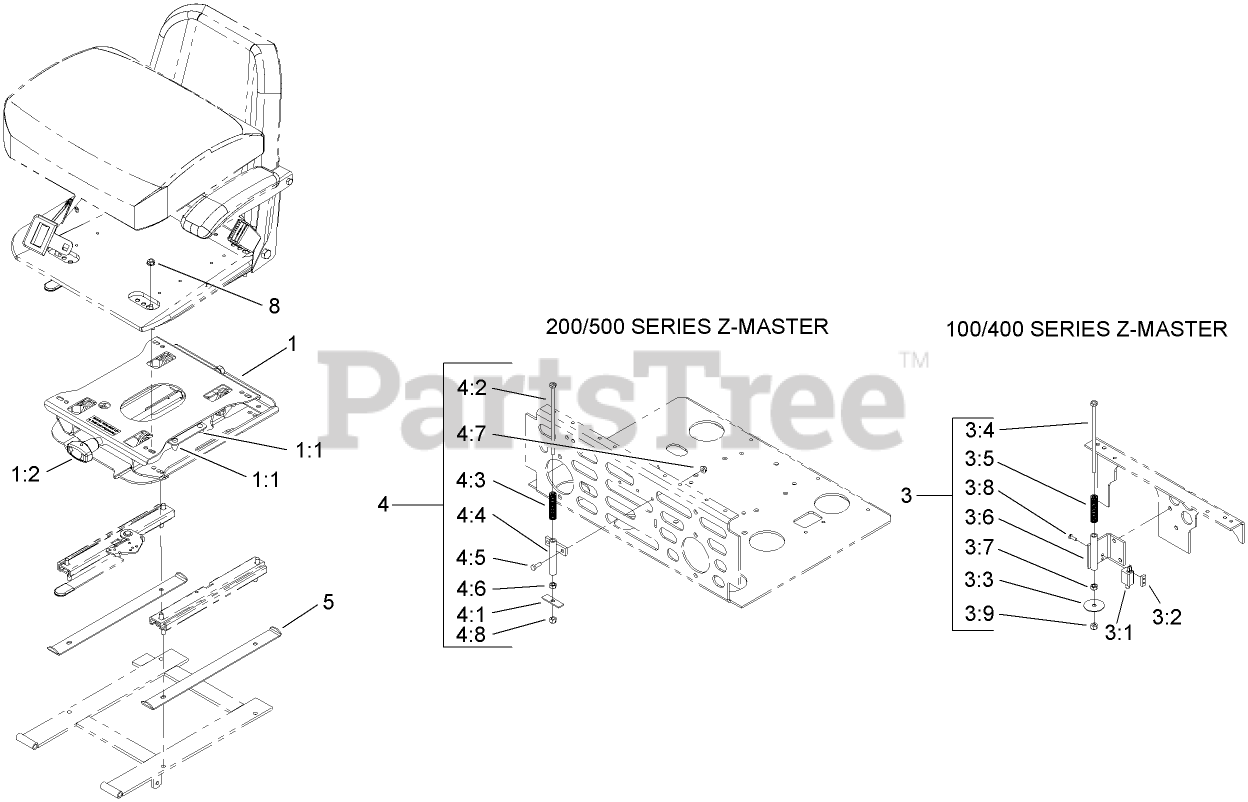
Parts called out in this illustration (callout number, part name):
1	SEAT-SUSPENSION
1:1	RUBBER STOPS KIT
1:2	ADJUSTMENT KNOB KIT
3	SEAT SWITCH ASM
3:1	SWITCH-CLOSED, NORMALLY
3:2	PLATE-TAPPED
3:3	WASHER
3:4	SCREW-HH
3:5	SPRING-COMPRESSION
3:6	BRACKET-SWITCH
3:7	NUT-HEX
3:8	SCREW-PPH
3:9	NUT-LOCK, NI
4	SEAT SWITCH ACTUATOR ASM
4:1	PLATE-SWITCH, SEAT
4:2	SCREW-HH
4:3	SPRING-COMPRESSION
4:4	MOUNT-SPRING, SEAT
4:5	SCREW-HH
4:6	NUT-HEX
4:7	NUT-HF
4:8	NUT-LOCK, NI
5	STOP-SEAT
8	NUT-HF
